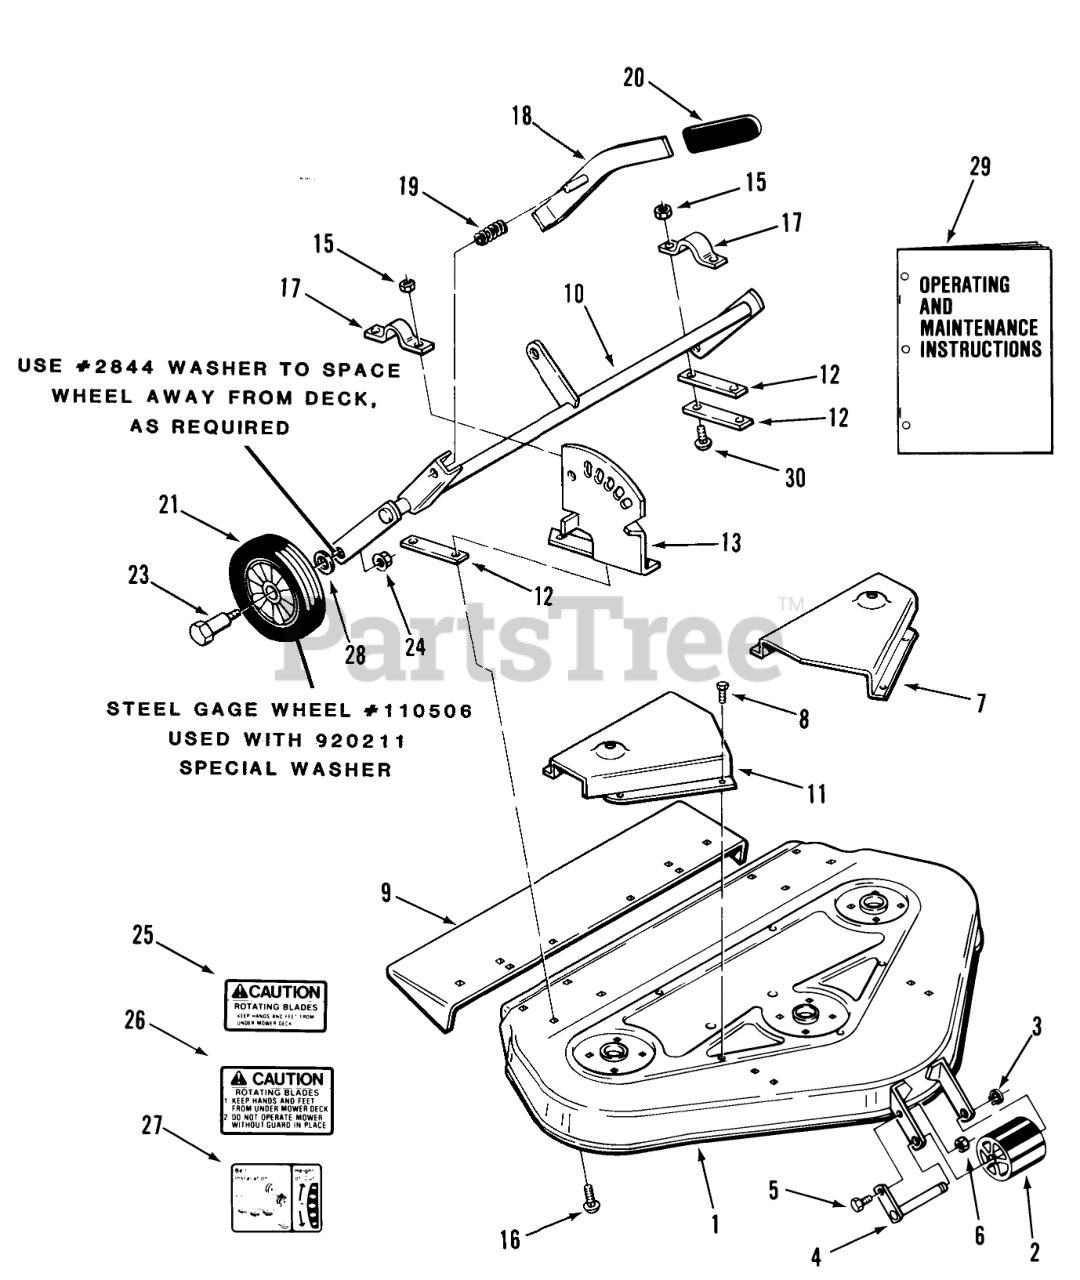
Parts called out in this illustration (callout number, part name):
1	Mower Deck
2	Roller
3	Retaining Ring
4	Roller Shaft
5	H H C S
6	Nut
7	Cover-Belt
8	Bolt
9	Chute Extension
10	Gage Wheel Support
11	Belt Cover RH
12	Strap
13	Quadrant
15	Nut
16	Bolt
17	CLAMP
18	Lever
19	SPRING-COMPRESSION
21	Wheel 6 x 1.75
23	BOLT-SHOULDER
24	Nut
25	Caution Decal
26	Decal-Caution
27	DECAL-HEIGHT & BELT
28	WASHER
29	Operating and Maintenance Instructions
30	Bolt
